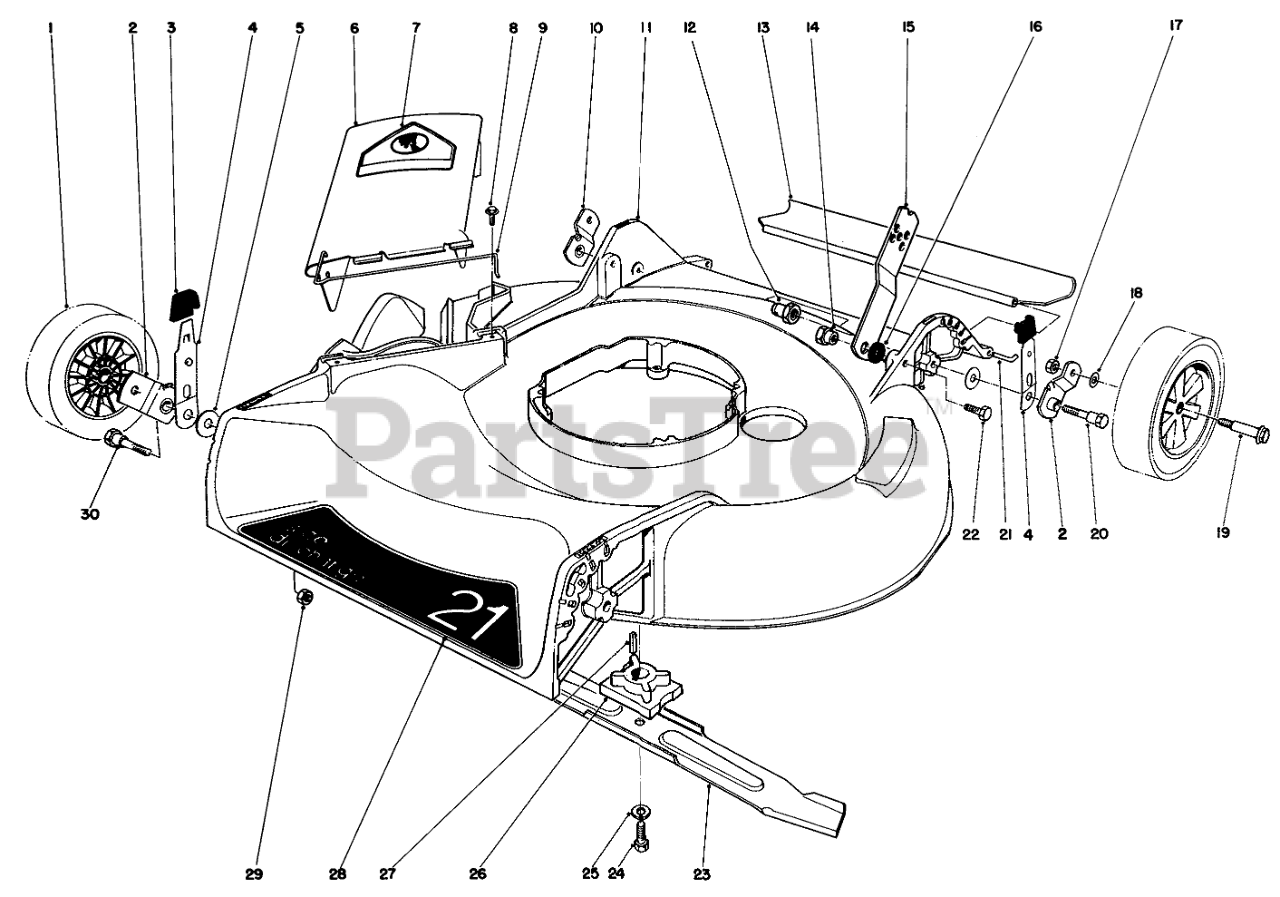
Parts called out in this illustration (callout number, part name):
1	WHEEL TIRE ASM 8 IN
2	Pivot Arm
3	KNOB-ARM
4	SPRING ARM ASM
5	WASHER-PIVOT
6	Deflector (Incl. Ref. #7 & 9)
7	DECAL-DANGER
8	SCREW AND WASHER ASM
9	SPRING HINGE
10	Pivot Arm
11	HOUSING/DECAL
12	HANDLE PIVOT NUT
13	REAR SAFETY SHIELD 21
14	HANDLE PIVOT NUT
15	Handle Latch
16	SPACER
17	Nut
18	WASHER
19	BOLT-WHEEL
20	5/16-18 PIVOT SCREW
21	SHIELD ROD
22	SCREW-HH
23	Blade
24	SCREW-HH
25	WASHER-LOCK
26	Blade Retainer
27	KEY-SQUARE
28	Decal-Side Discharge
29	NUT-LOCK, NI
30	PIVOT SCREW
